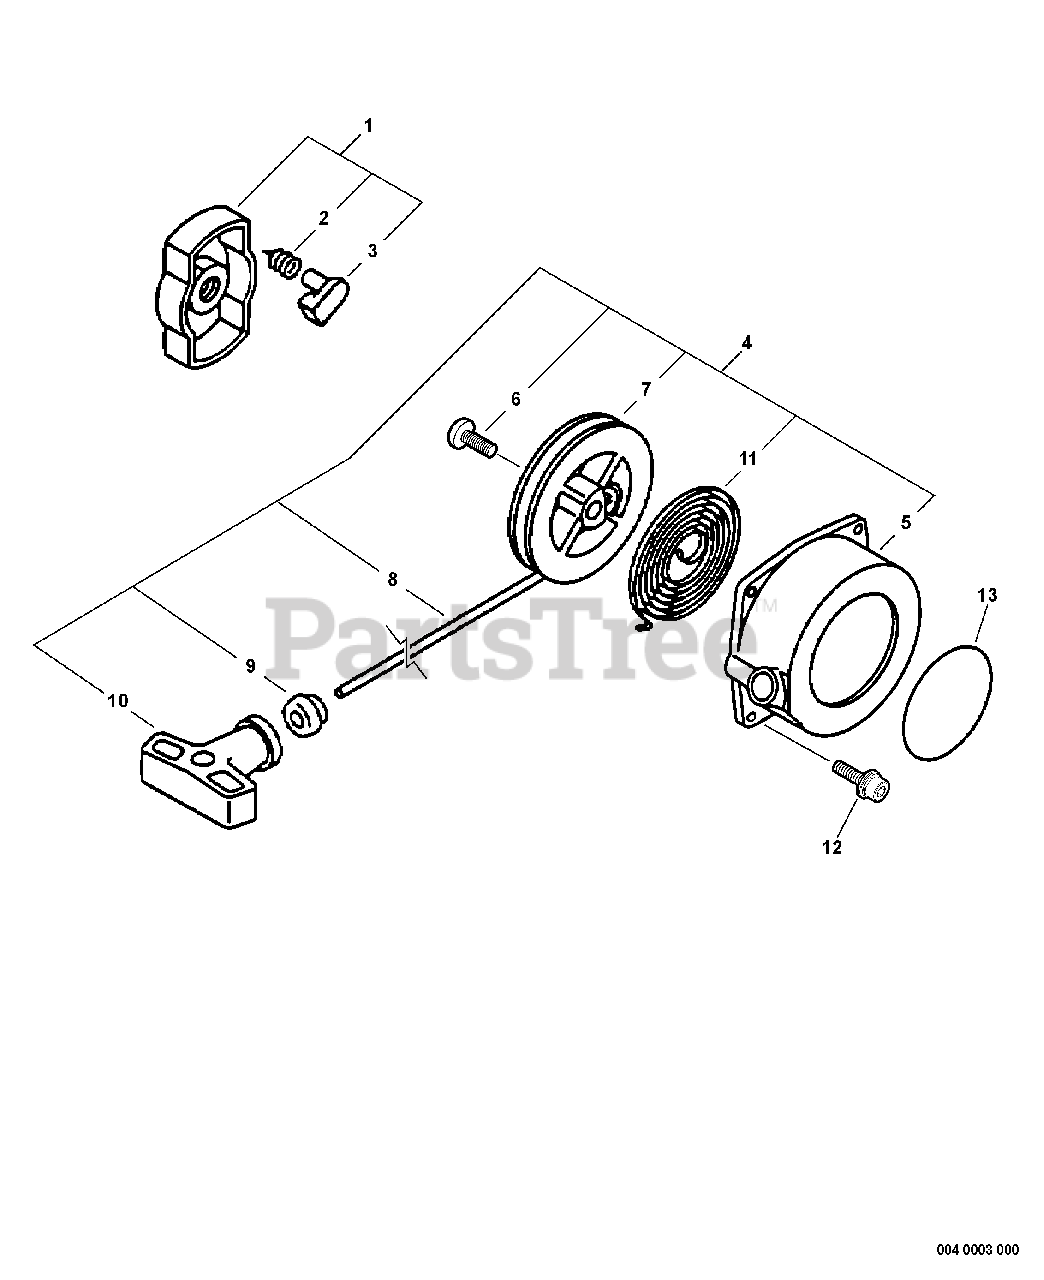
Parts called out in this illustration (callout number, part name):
1	STARTER PAWL ASSY
2	SPRING, RETURN
3	PAWL, STARTER - BLACK
4	STARTER ASSY
5	CASE, STARTER
7	REEL, ROPE
8	ROPE, STARTER - 3X1000
9	GUIDE, ROPE
10	GRIP, STARTER
11	SPRING, REWIND
12	SCREW - 4X16
13	LABEL - ECHO
